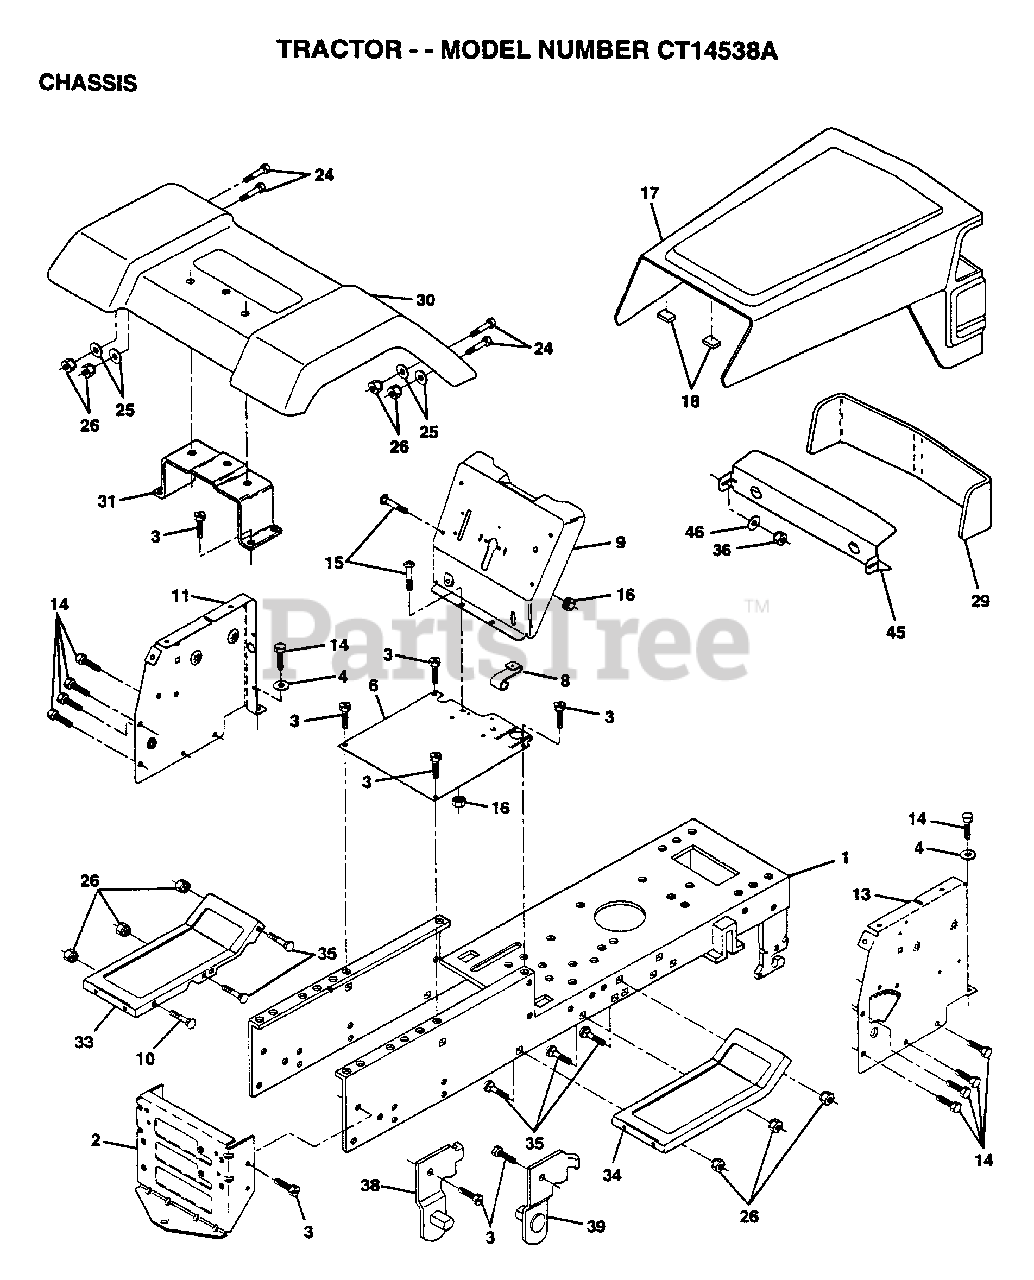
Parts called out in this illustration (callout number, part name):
1	CHASSIS.WLD.11GA
3	SCREW
4	WASHER
8	"CLIP,INSULATOR"
9	DASH SILKSCRN 1
11	DASH PANEL LH
14	SCREW LT
15	SCREW
17	HOOD/GRILL ASM
24	BOLT
25	WASHER
26	NUT
29	LENS SERVICE KIT
30	FENDER
31	BRKT FENDER
33	FOOTREST LH
34	FOOTREST RH
35	BOLT
36	PAL NUT LT
38	BRACKET ASM LH
39	BRACKET ASM RH
46	RETAINER
